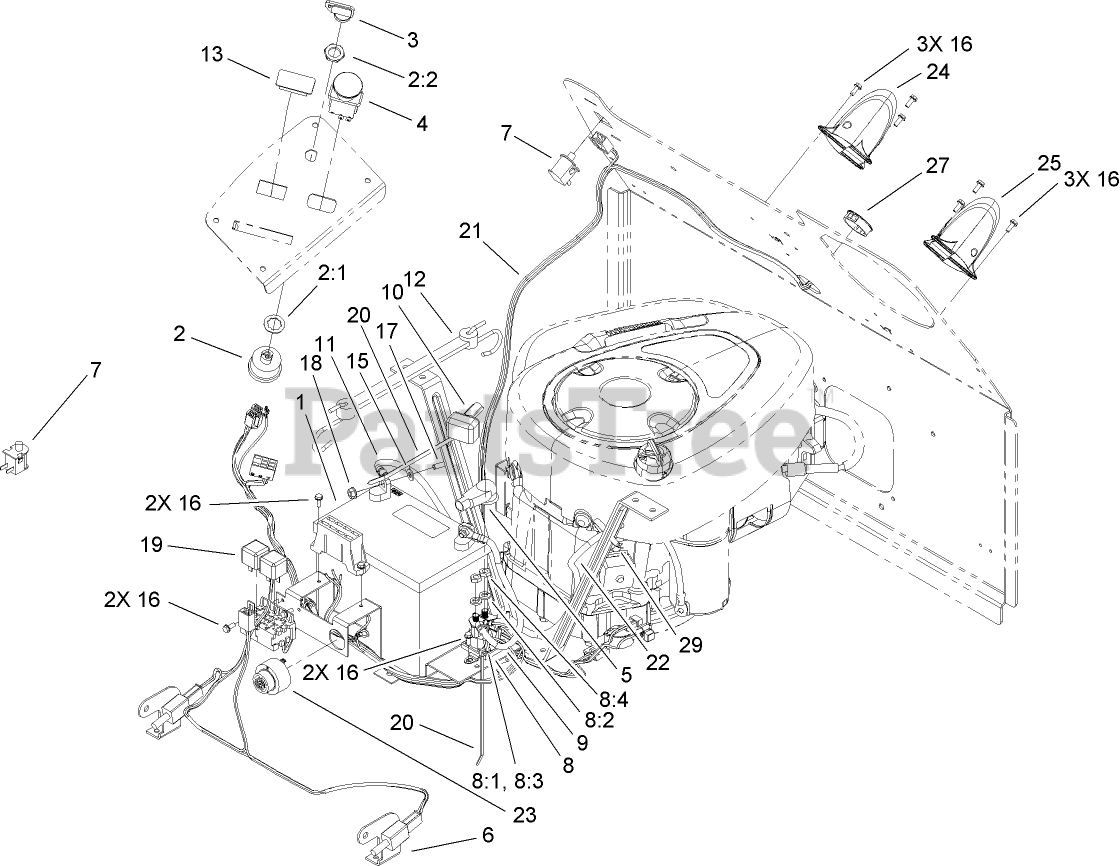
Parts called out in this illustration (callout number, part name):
2:1	WASHER-LOCK
2:2	NUT-HH
3	KEY-IGNITION
4	SWITCH-PTO,ON-ON-NONE
5	BOOT-TERMINAL
6	SWITCH
7	SWITCH-BAIL
8:1	WASHER-LOCK
8:2	WASHER-LOCK
8:3	NUT-HEX
8:4	NUT-JAM
9	CABLE-BATTERY, POSITIVE
10	BOOT-INSULATOR, TERMINAL
11	CABLE-NEGATIVE, BLACK
12	HOLDDOWN-BATTERY
13	PLUG-HOLE
15	WASHER-FLAT
16	SCREW-TAPTITE
17	SCREW-HH
18	NUT-HF
19	RELAY
20	TIE-CABLE
21	HARNESS-DIRECT COLLECT
22	WIRE-21 INCH
23	ALARM-TONE, DUAL
24	BAG SENSOR ASM
25	BAG SENSOR ASM
27	BUSHING-HARNESS, WIRE
29	CLAMP-HOSE
